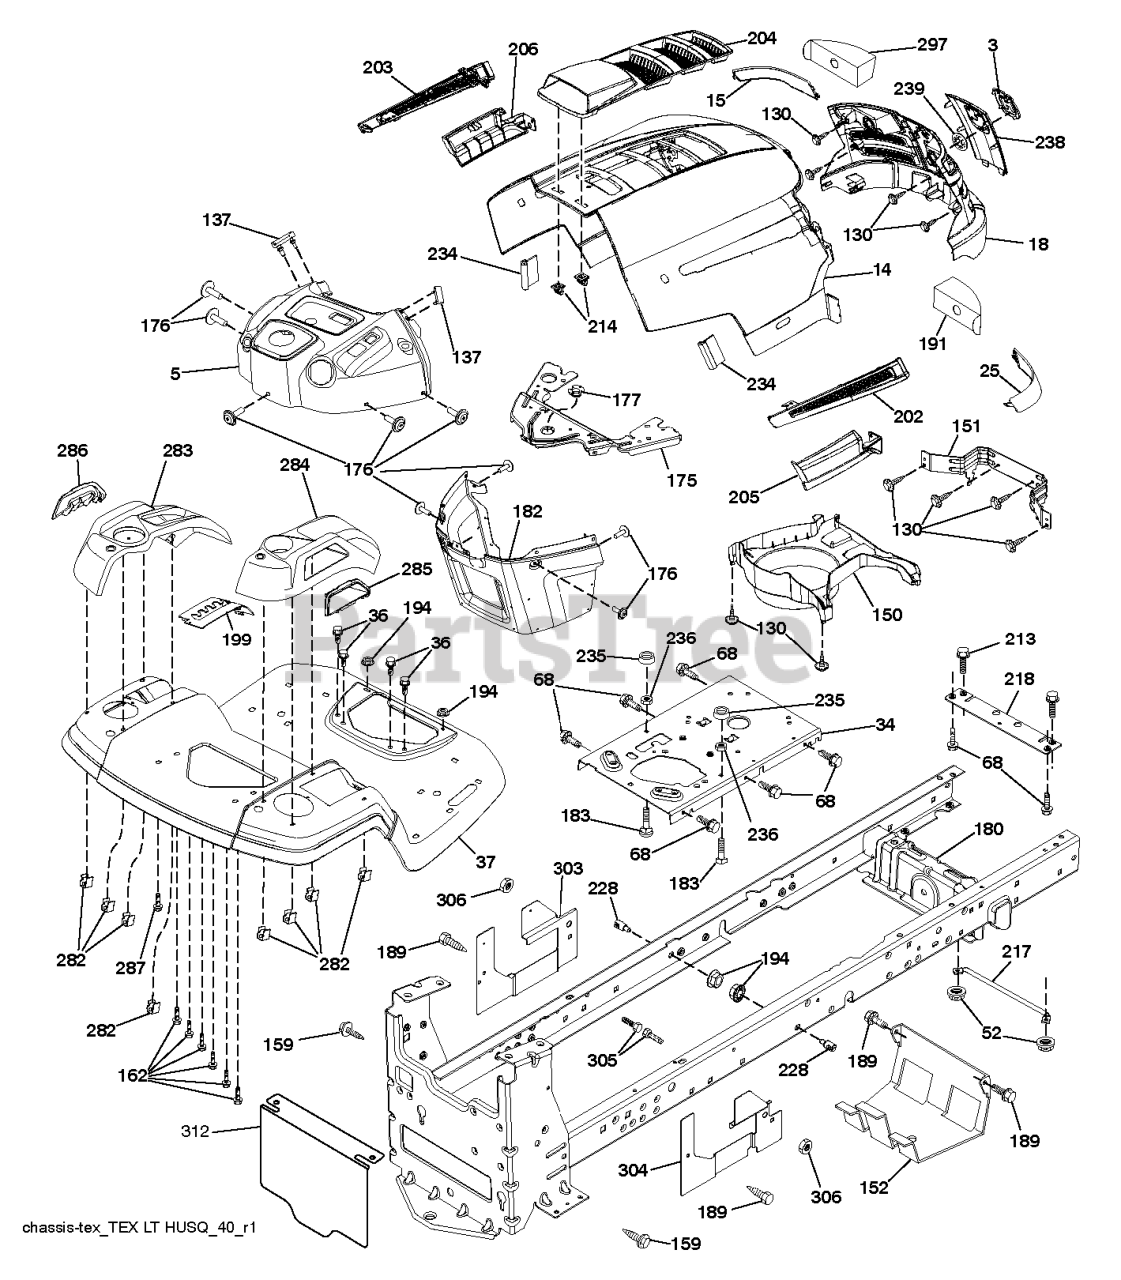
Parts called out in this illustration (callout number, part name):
3	RP LOGO
5	DASH
14	HOOD.HUSQVARNA.LT.ORANGE
15	LENS.HUSQVARNA LT.LH
18	GRILLE.SVC.HUSQVARNA.LT.GREY
25	LENS.HUSQVARNA LT.RH
34	PLATE.ENGINE.WELDED.CHASSIS
36	SCREW 5/16"
37	FENDER.TLT.FS.W/CUPHLD.ORANGE
52	LOCKNUT
68	Screw 5/16-18 x 1/2 Hex, Self Tapping 5/16-18 x 1/2
130	SCREW.#10 X 0.750.BOS
137	BUMPER DASH
151	BRACKET PIVOT
152	SHIELD.BROWNING.W/TEX
159	SCREW, 3/8-16X3/4
162	SCREW.HI-LO.CONSOLE
175	CROSSMEMBER
176	SCREW.#10-24X5/8.RN.QU
177	BUSHING STEERING
180	CHASSIS
182	DASH.LOWER.PREDATOR LT
183	BOLT.5/16-18X1-1/4 FULL THD
189	SCREW
191	INSERT.REFLECTIVE.RH.
194	NUT LOCK HEX FLANGE 5/16-18
199	PLATE.DECK.LIFT.HUSQ.LT
202	VENT SIDE HOOD LH
203	VENT SIDE HOOD RH
204	VENT TOP HOOD
205	SKIRT SIDE RH
206	SKIRT SIDE LH
213	BOLT
214	CLIP.RETAINER.TINNER.
217	ROD.PIVOT.HOOD
218	X-PIECE.HOOD.STOP.NON/
228	STUD.FASTNER.W/ANTI-ROTATE
234	BUMPER.HOOD.TEX.HUSQVARNA
235	SPACER FENDER
236	NUT.CENTERLOCK.5/16-
238	TRIM
282	CLIP.RETAINER.CONSOLE.LT.HUSQ
283	CONSOLE.DECK.LIFT.HUSQ.N/FR.GR
284	CONSOLE.SHFT.HYD,HUSQL
285	CONSOLE INSERT RH
286	CONSOLE.INSRT.LH.HUSQ.LT.BLACK
287	SCREW 1/4X20
297	INSERT REFLECTIVE
303	SHIELD CHASSIS LEFT
304	SHIELD CHASSIS RIGHT
306	NUT LOCK FLG 3/8-16 UNC
